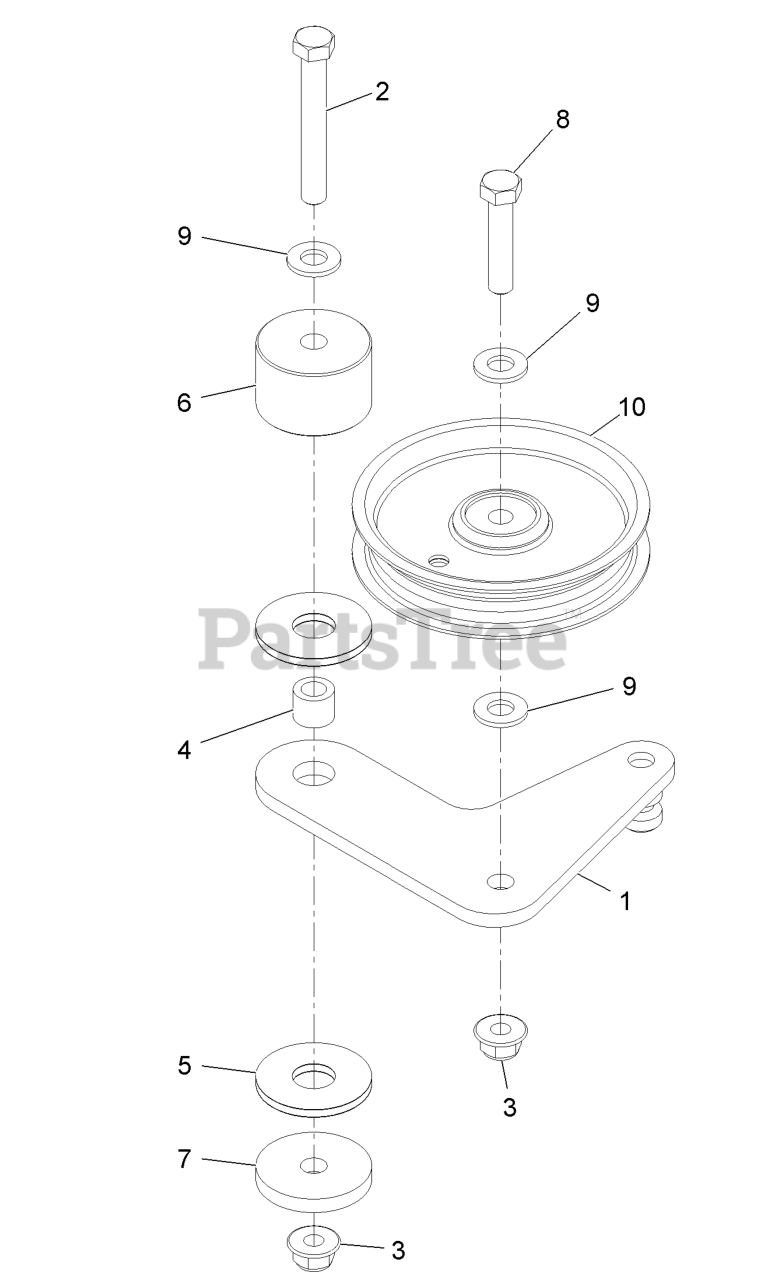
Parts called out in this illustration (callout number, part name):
1	PLATE-IDLER
2	SCREW-HH
3	NUT-HF, NI
4	BUSHING-LEVER, LIFT
5	WASHER-FRICTION, COMPOSIT
6	HUB-IDLER
7	WASHER-PLAIN
8	SCREW-HH
9	WASHER-FLAT
10	PULLEY-IDLER
